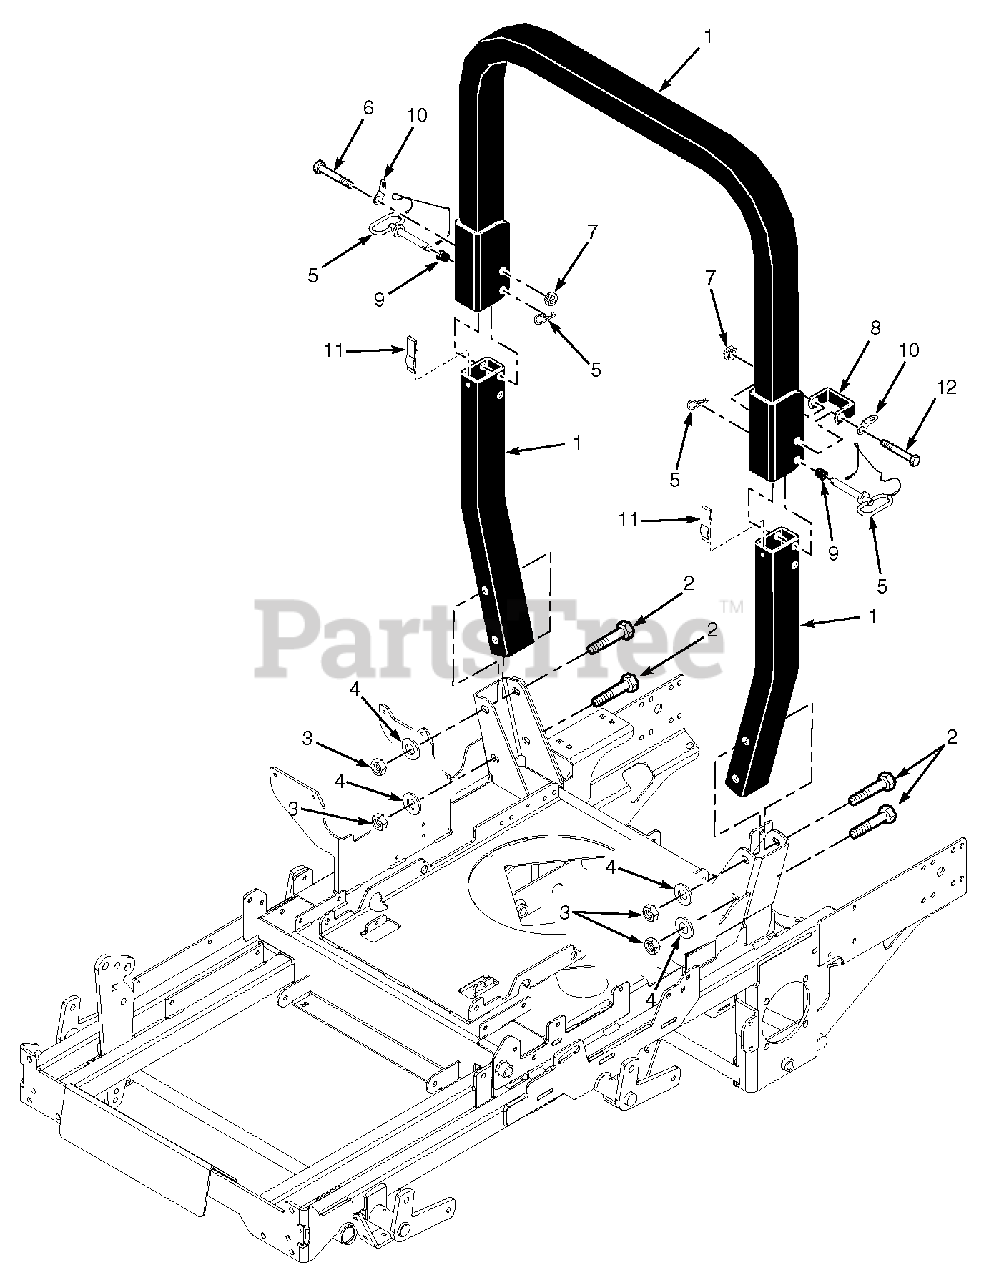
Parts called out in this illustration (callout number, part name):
1	STT, ROPS
2	Bolt, Hex Head 1/2-13 x 4-1/4"
3	Nut, Center Lock 1/2-13
4	Flatwasher, 1/2-.562 x 1.375 x .109
5	Pin Assembly, ROPS Hinge
6	Bolt, Hex Head 1/2-13 x 3-1/4"
7	Nut, Elastic Stop 1/2-13
8	Stop, ROPS
9	Spring, ROPS
10	Clip, ROPS
11	Spring, ROPS
12	Bolt, Hex Head 1/2-13 x 3-3/4"
